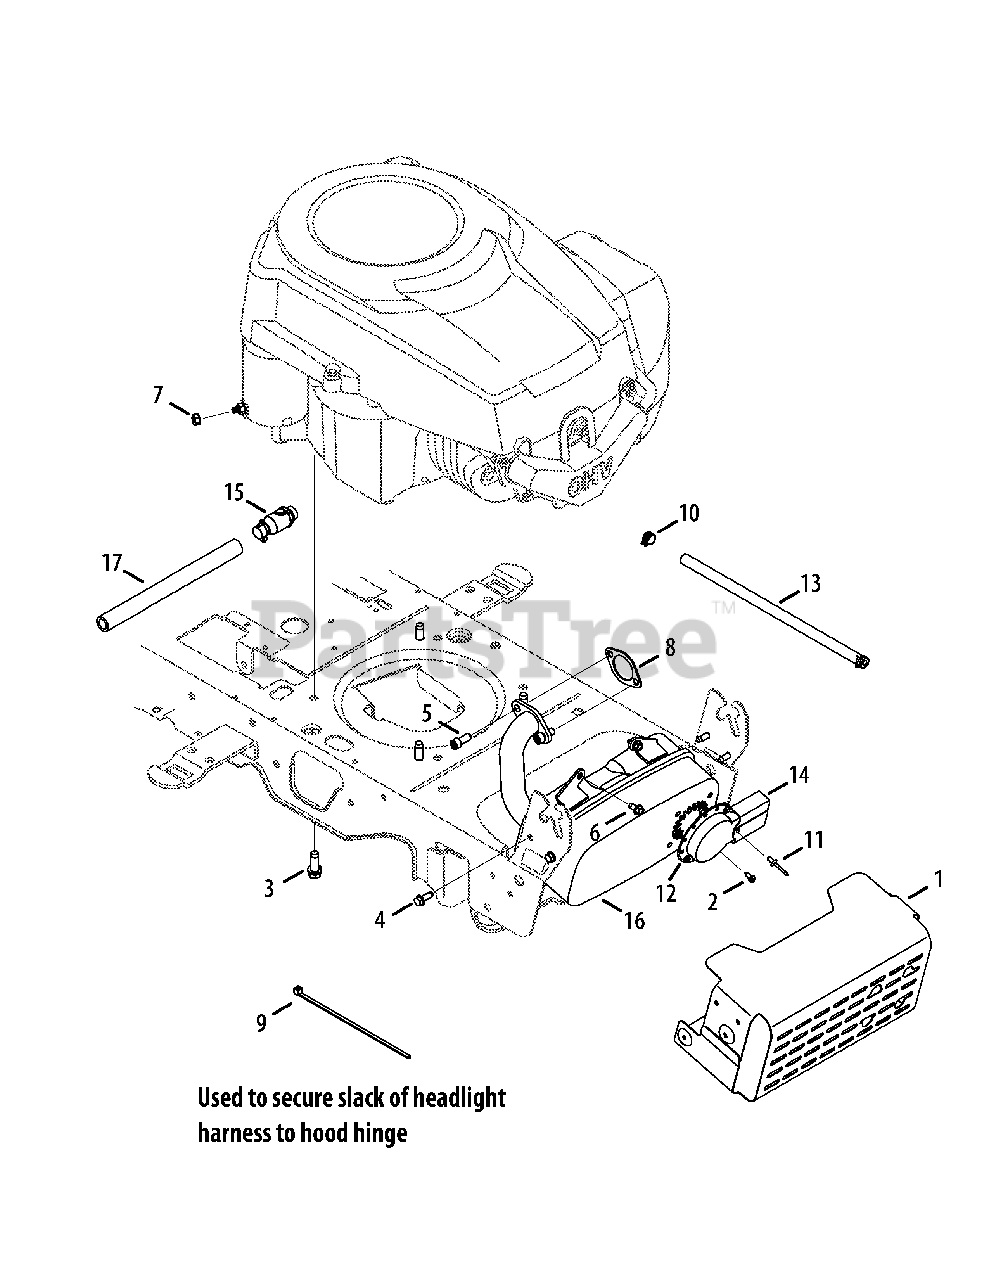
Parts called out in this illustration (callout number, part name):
1	Shield Ass’y, Muffler
2	Screw, Ab, #8-18, 0.500,
3	Screw, Self-tapping, 3/8-16, 1.000,
4	Screw, Self-tapping, 1/4-20, 0.500,
5	Screw, Socket Head, 5/16-18, .750
6	Screw, Self-tapping, 1/4-20x.625,
7	Nut, Sems, 1/4-20
8	Gasket, Exhaust
9	Cable, Tie, 3/16 x .05 x 7.4
10	Clamp, Hose, .490 Dia.
11	Rivet, Pop, .188 Dia x .300
12	Deflector, Muffler
13	Hose, Fuel, Low Permeation, 1/4
14	Deflector, Muffler, Long
16	Muffler, Single, Kohler
17	Hose, Extension, Oil Drain
